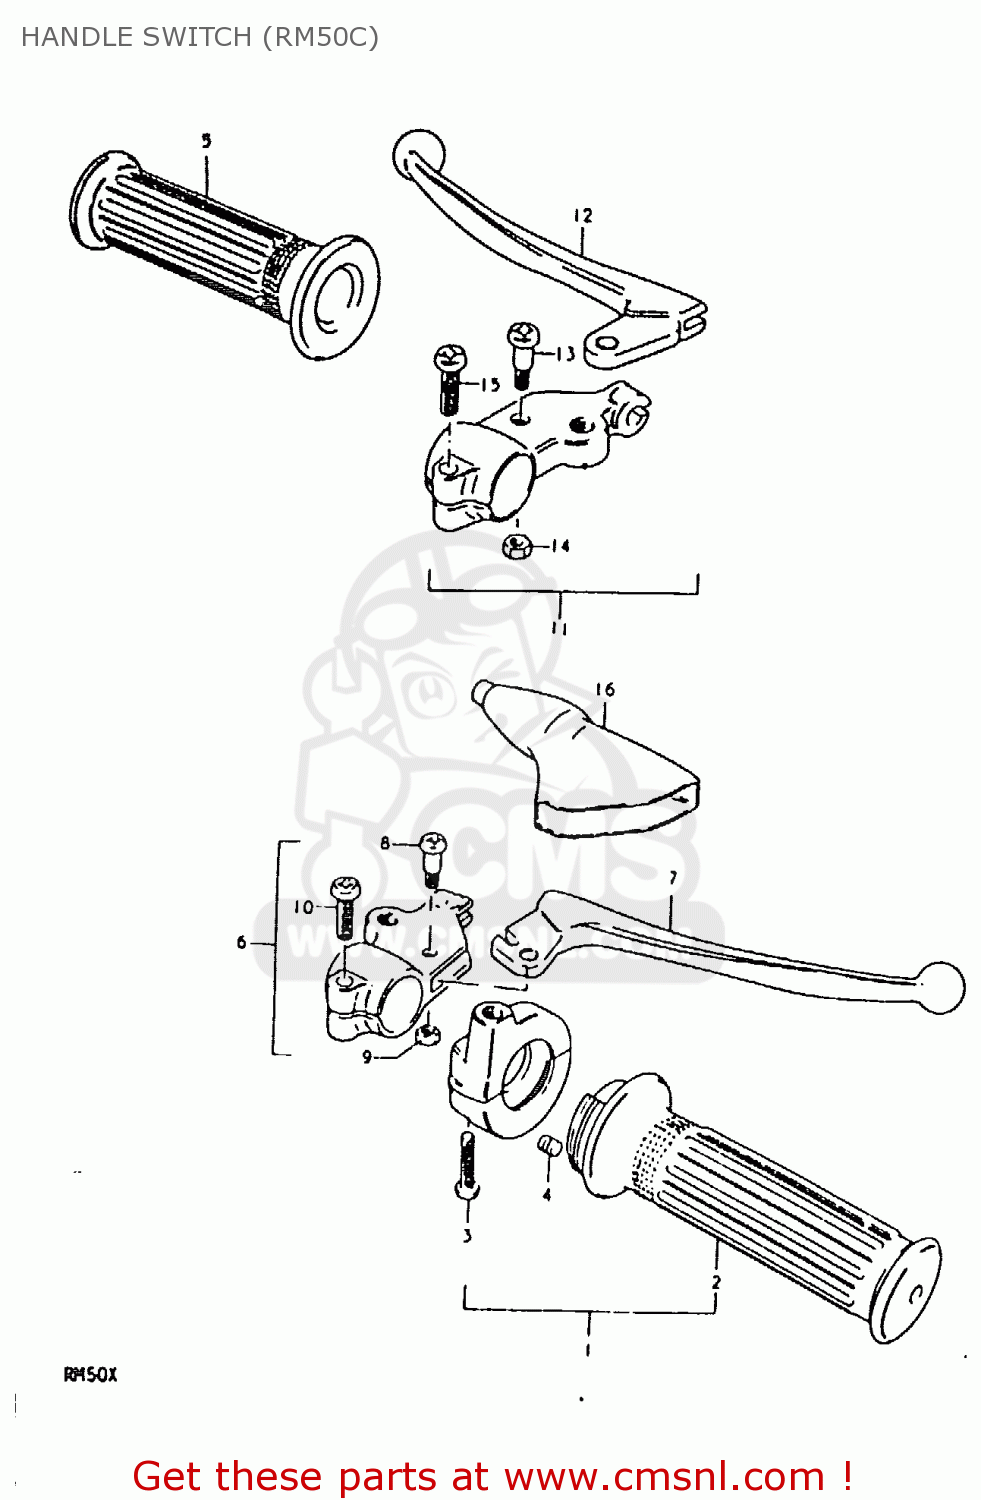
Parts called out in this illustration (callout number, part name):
1	CASE ASSEMBLY,THROTTLE
2	GRIP,THROTTLE
3	SCREW
4	PIECE,THROTTLE END
5	GRIP,L
6	LEVER ASSEMBLY,BRAKE
7	LEVER,BRAKE
8	BOLT,LEVER
9	NUT,LEVER BOLT
10	SCREW
11	LEVER ASSEMBLY
12	LEVER,CLUTCH
13	BOLT,LEVER
14	NUT
15	SCREW
16	COVER,CLUTCH LEVER
